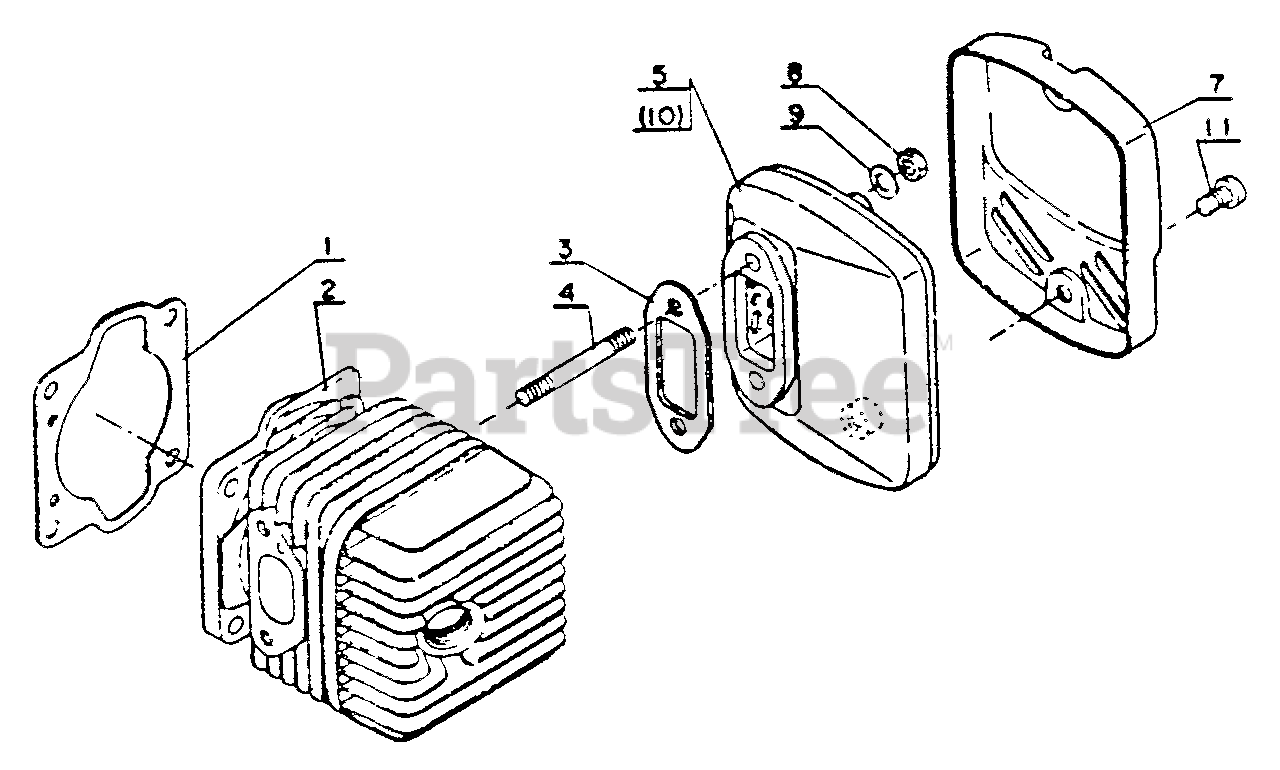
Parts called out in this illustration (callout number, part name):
1	GASKET, CYLINDER
2	CYLINDER
3	GASKET, EXHAUST
5	MUFFLER ASSY
7	LID, MUFFLER
8	LOCKNUT - 5
9	WASHER - 5
11	SCREW - 5X8
12	BOLT - 5X8
13	LOCKWASHER - 5
